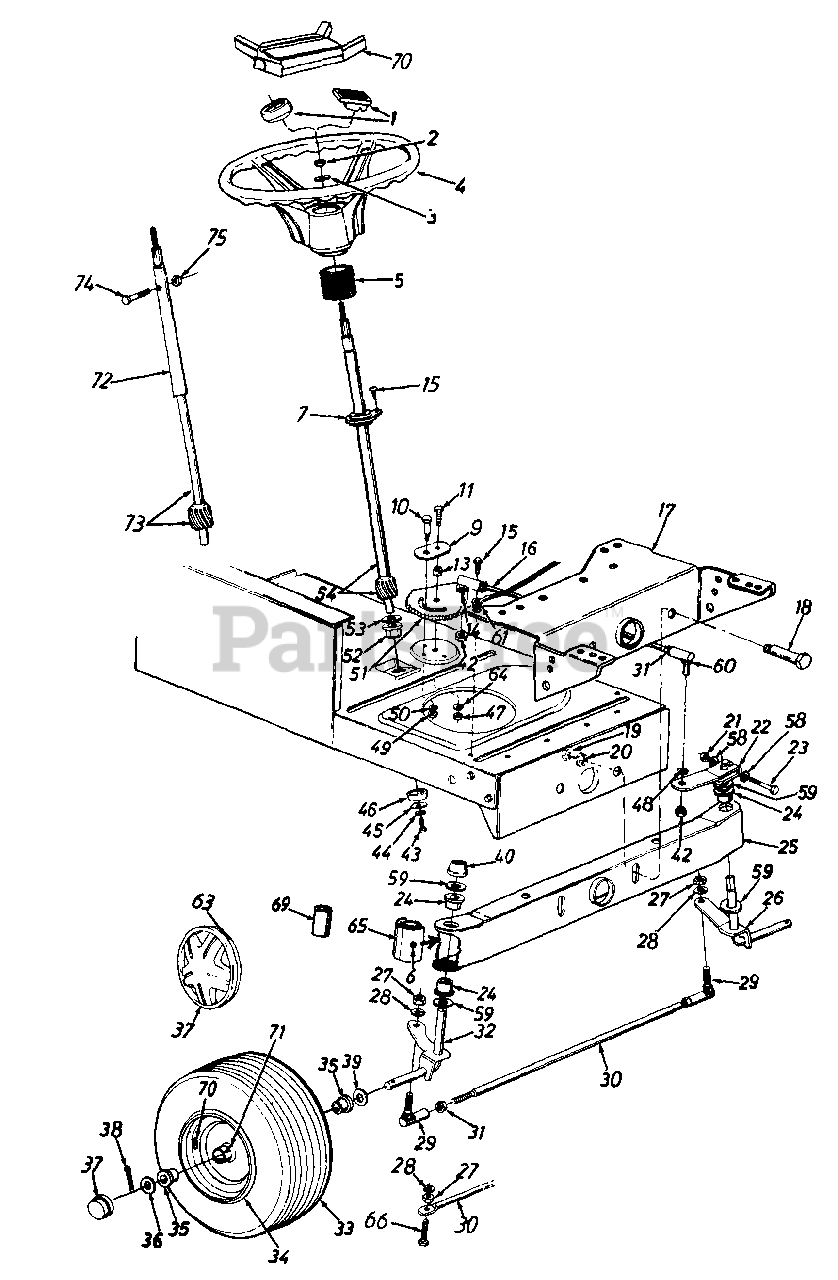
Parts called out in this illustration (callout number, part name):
1	Steering Wheel Cap
2	Hex L-Nut 5/16-24 Thd.
3	Belleville Wash .345" I.D.
4	Steering Wheel (3 Spoke)
5	Steering Bellow - 4.5"
6	Grease Fitting
7	Flange Bearing .628" I.D. x 1.36 O.D.
9	Retainer Plate
10	Shoulder Bolt .437" Dia. x .35 Lg. 5/16-18 Thd.
11	Hex Bolt 3/8-24 x 1.0" Lg. (Gr. 5)
13	Spacer.380" I.D. x .625" O.D. x .227
14	L-Wash. 3/8" I.D. (H.D.)
15	Hex Wash. Hd. Self-Tap Scr.
16	Steering Drag Link
18	Shoulder Bolt .498" Dia. x 2.04 Lg. 3/8-16 Thd.
19	Hex Nut 3/8-16 Thd.
20	L-Wash. 3/8" I.D.
21	Hex L-Nut 5/16-24 Thd.
22	Steering Arm Front Axle
23	Hex Bolt 5/16-24 x 2.00" Lg. (Grade 5)
24	Hex Flg. Brg .632 I.D.
26	Front Axle Ass'y.- L.H.
27	Hex Nut 3/8-24 Thd.
28	L-Wash. 3/8" I.D.
29	Ball Joint 3/8-24 Thd.
30	Tie Rod (Adjustable)
31	Hex Jam Nut 3/8-24 Thd.
32	Front Axle Ass'y.- R.H.
33	Wheel Ass'y. Comp.
34	Front Wheel Rim Only
35	Bearing
36	Fl-Wash .635 I.D. x 1.59" O.D.
37	Front Wheel Hub Cap
38	Cotter Pin 1/8" Dia. x 1.25"
39	Fl-Wash .640" I.D. x 1.24" 0.0.
40	Push Cap 5/8" Dia. Rod
42	Hex Jam Nut 3/8-24 Thd.
43	Hex L-Bolt 5/16-18 x .62"
44	L-Wash. 5/16" I.D.
45	Fl-Wash .33" I.D. x 1.25" O.D.
46	Spacer (Plastic)
47	Hex Cent. L-Nut 3/8-24 Thd.
48	L-Wash. 3/8" I.D.
49	Hex Cent. L-Nut 5/16-18 Thd.
50	L-Wash. 5/16" I.D.
51	Steering Gear Segment
52	Hex Flg. Brg .634 I.D.
53	Fl-Wash. (Hardened)
54	Steering Shaft
58	Wave-Wash .32" I.D. x .62" O.D.
59	Fl-Wash. (Hardened)
60	Drag Link Ball Joint 3/8-24 Thd.
61	Ext. L-Wash. 5/16" I.D.
63	Spring Clip
64	Bell-Wash .39" I.D. x 1.38" O.D.
65	Pivot Bar End Cap
66	Hex Bolt 3/8-24 x 1.5" Lg. (Gr. 5)
69	Plastic Tube 1.54" Lg.
70	Steering Wheel Insert
72	Upper Steering Shaft
73	Lower Steering Shaft
74	Hex Bolt 1/4-20 x 1.25" Lg.
75	Hex L-Nut 1/4-20 Thd.
